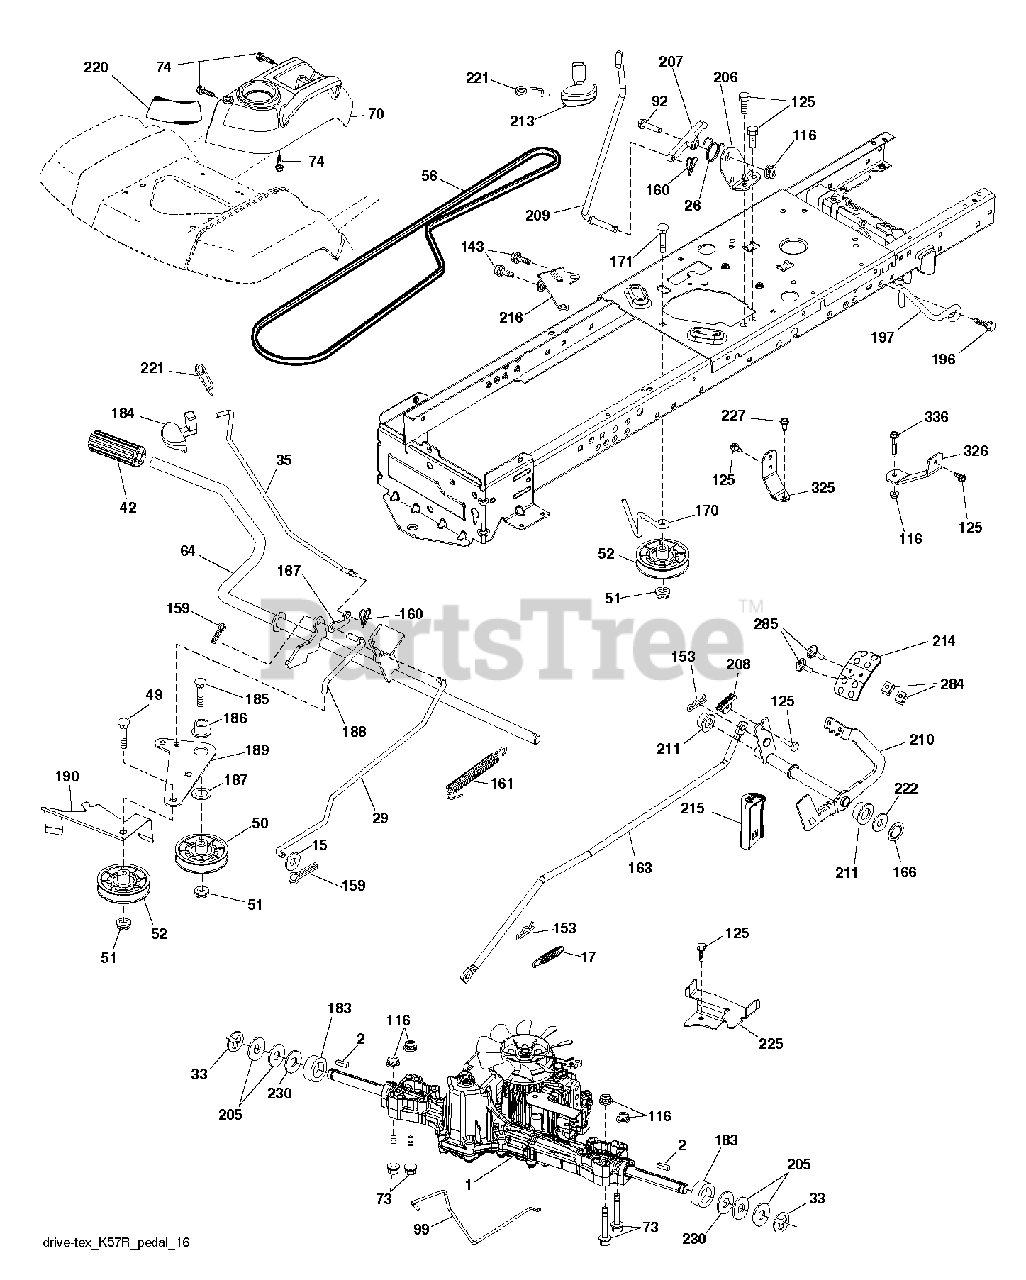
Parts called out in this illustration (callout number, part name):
2	SQUARE KEY
15	WASHER
17	SPRING.BRAKE.K46.GREEN
26	SPRING.RETURN.CRUISE
29	ROD.BRAKE.K46
35	ROD .BRAKE. PARKING. GT. HUSQ.
42	PEDAL COVER T
50	IDLER.FLAT.910.OFFSET
51	NUT LOCK FLG 3/8-16 UNC
52	IDLER.V-GROOVE.910.OFFSET
56	V-BELT.MOWER.92.40.42/K46
64	SHAFT.ASM.PEDAL.BRK.CNTR
70	CONSOLE.ASM.RH.GT.FC.HUSQ
74	SCREW.HI-LO.CONSOLE
92	BOLT
99	ROD.SPRING.BYPASS.K46.LT.Z
116	NUT LOCK HEX FLANGE 5/16-18
125	SCREW
143	SCREW LT
153	RETAINER M
159	COTTER PIN
160	RETAINER CLIP
161	SPRING, RETURN LT
163	ROD.CONTROL.K57R.K46
166	NUT.PUSH.625
167	LATCH.BRAKE.SPRING
170	KEEPER.V-IDLER.CENTER.
183	SPACER AXLE
184	RB HANDLE.PARKG.BRK.HUS/PRED
186	SPACER.RETAINER
187	WASHER 12/32X2X10GA
188	RP LINK.CLUTCH.GROUND.DRIVE
189	BELLCRANK.GROUND.DRIVE.TEX.
190	KEEPER.BELLCRANK.DRIVE
196	SCREW 3/8-16X1
197	CLUTCH.ANTIROTATION.WIREFORM.
206	BRACKET.MOUNT.CRUISE.LATCH
207	LATCH.CONTROL.CRUISE
208	GEAR.SECTOR.CONTROL.CR
209	ROD.CONTROL.CRUISE.GT.
210	ROCKER.ASM.PEDAL.CONTR
211	BEARING.NYLON
213	KNOB.CONTROL.CRUSIE.HU
214	PEDAL.FORWARD.HUSQVARNA.DEALER
215	PEDAL RUBBER REVERSE
216	BRACKET.PULLEY.IDLER.W/TEX
220	REFLECTOR.RH.TEX GT
221	RETAINER.SPRING.CLIP.H
222	WASHER 21/32 X 1-1/4 X 10 GA.
225	KEEPER.BELT.TRANSAXLE.K46
227	SCREW
230	WASHER.HARDENED
284	NUT.U-CHNL.1/4-20.550DP.350PNL
285	SCREW.MACHINE.CR.1/4-20
325	BRACKET.TRQ.STP.46.20".TIRE.LH
326	BRCKT.PNT.TRQ.STP.46.20TIRE.RH
336	BOLT.5/16-18X1-3/4.FLANGED.HEX
